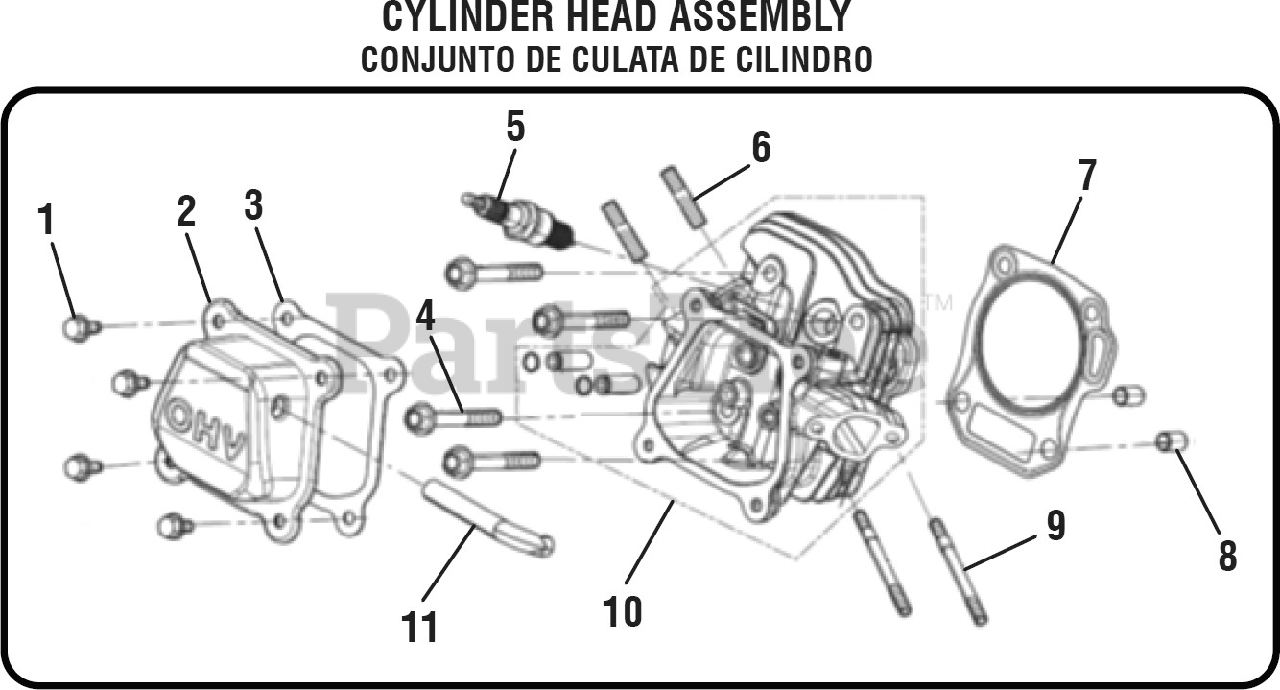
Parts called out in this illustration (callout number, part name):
2	Cylinder Head Cover Assembly
3	Cylinder Head Cover Gasket
4	Cylinder Head Bolt
5	Spark Plug
6	Stud
7	Cylinder Head Gasket
9	Stud
10	Cylinder Head Assembly
11	Breather Tube
